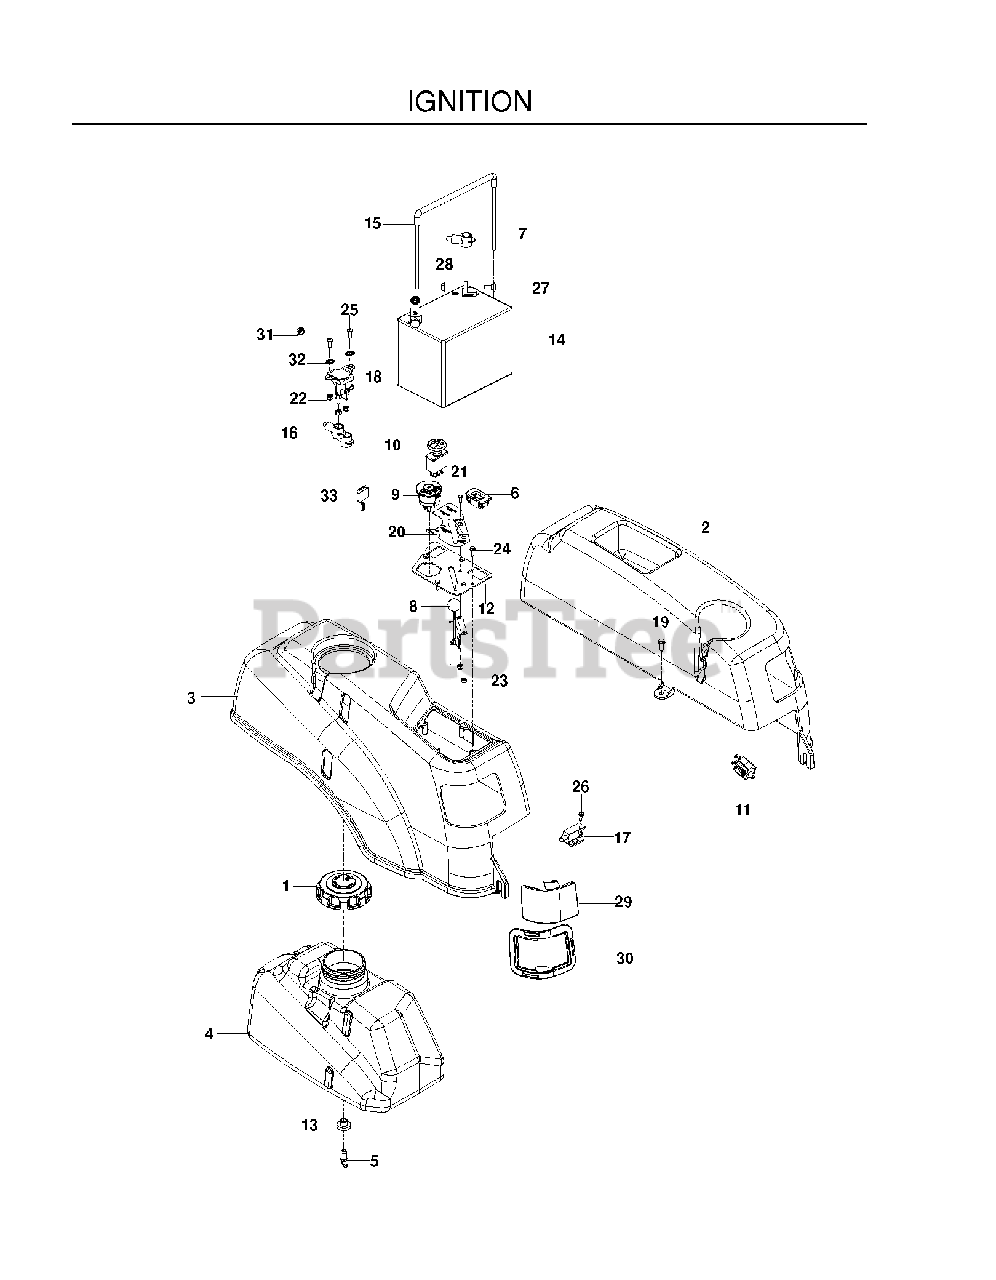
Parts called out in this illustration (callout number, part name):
1	FUEL CAP, HTC
2	FENDER, LT
3	RP FENDER, RT
5	STEM, FUEL TANK
6	HOUR METER
8	CABLE, THROTTLE
9	RP IGNITION SWITCH
10	RP SWITCH, BLADE
11	SWITCH, BRAKE 3P
12	PLATE.CONTROL.CONSOLE.BLACK
13	RUBBER GROMMET
14	BATTERY, 12 V 330 AMP
15	BATTERY TIE DOWN ASSEMBLY
16	TERMINAL COVER-SM
17	SWITCH, INTERLOCK
19	BOLT 1/4-20 X 1/2 HWST
20	Decal, Ignition Console
21	HCS #10-24 X 1/2
22	RP_NUT 1/4-20 NYLOC
23	NUT 10-24 NYLOC
24	SCR #10-12X3/4 HEX WAS HD ZD
25	SCR 1/4-20 X 5/8 BTN SKT HD ZD
26	SCREW #10 X 1/2 SELF TAPPING
27	BOLT 5/16C X 3/4" CARRIAGE
28	5/16-18 NYLOC FLANGE NUT
29	LENS, COLORED LEFT
30	LEFT HEADLIGHT RIM GREY
31	JAM NUT 1/4C (2 2 PW01)
32	WASHER 1/4 INT TOOTH
33	KEY
